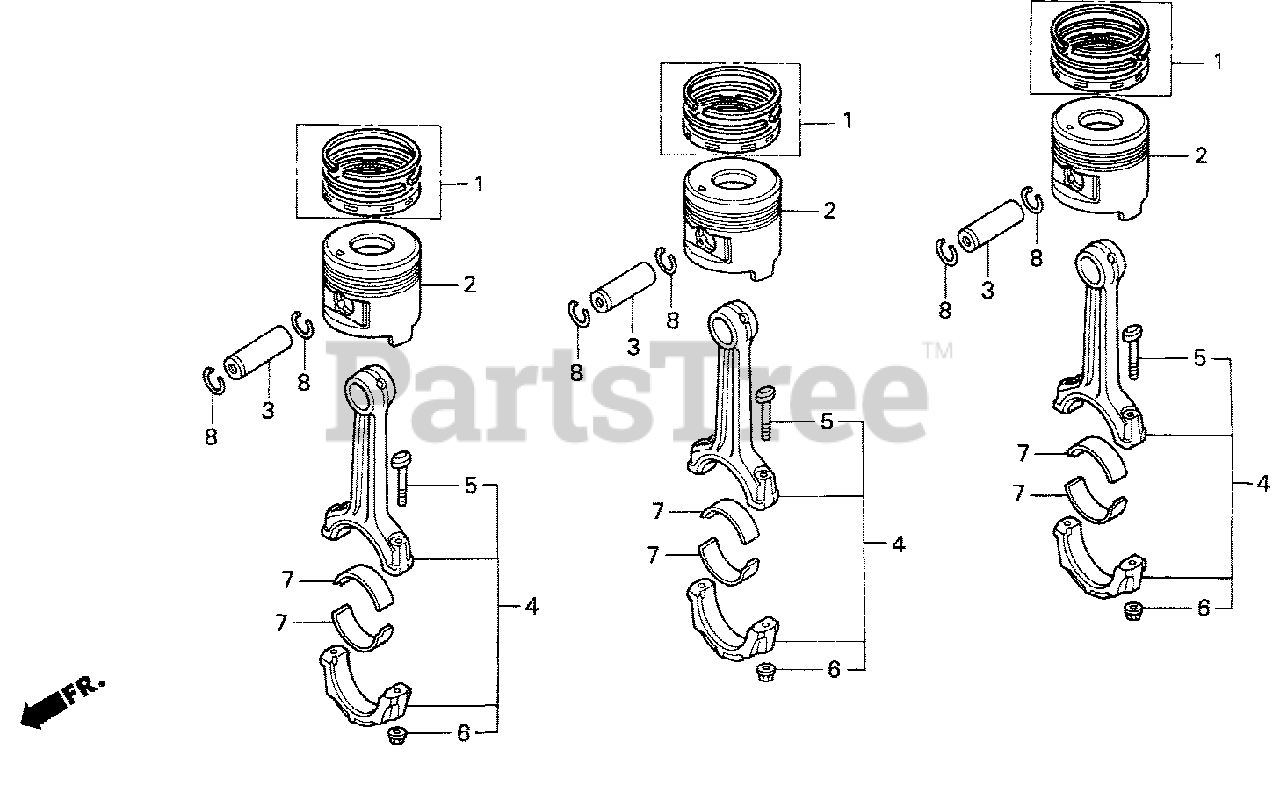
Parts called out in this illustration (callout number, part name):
1	RING SET, PISTON (STD)
1	RING SET, PISTON (OS 0.25)
1	RING SET, PISTON (OS 0.50)
2	PISTON (STD)
2	PISTON (OS 0.25)
2	PISTON (OS 0.50)
3	PIN, PISTON
4	ROD ASSY., CONNECTING
5	BOLT, CONNECTING ROD (8X51)
6	NUT, CONNECTING ROD
7	BEARING A, CONNECTING ROD (BLUE)
7	BEARING B, CONNECTING ROD (BLACK)
7	BEARING C, CONNECTING ROD (BROWN)
7	BEARING D, CONNECTING ROD (GREEN)
7	BEARING E, CONNECTING ROD (YELLOW)
7	BEARING, CONNECTING ROD (F)(PINK)
7	BEARING G, CONNECTING ROD (RED)
8	CLIP, PISTON PIN
